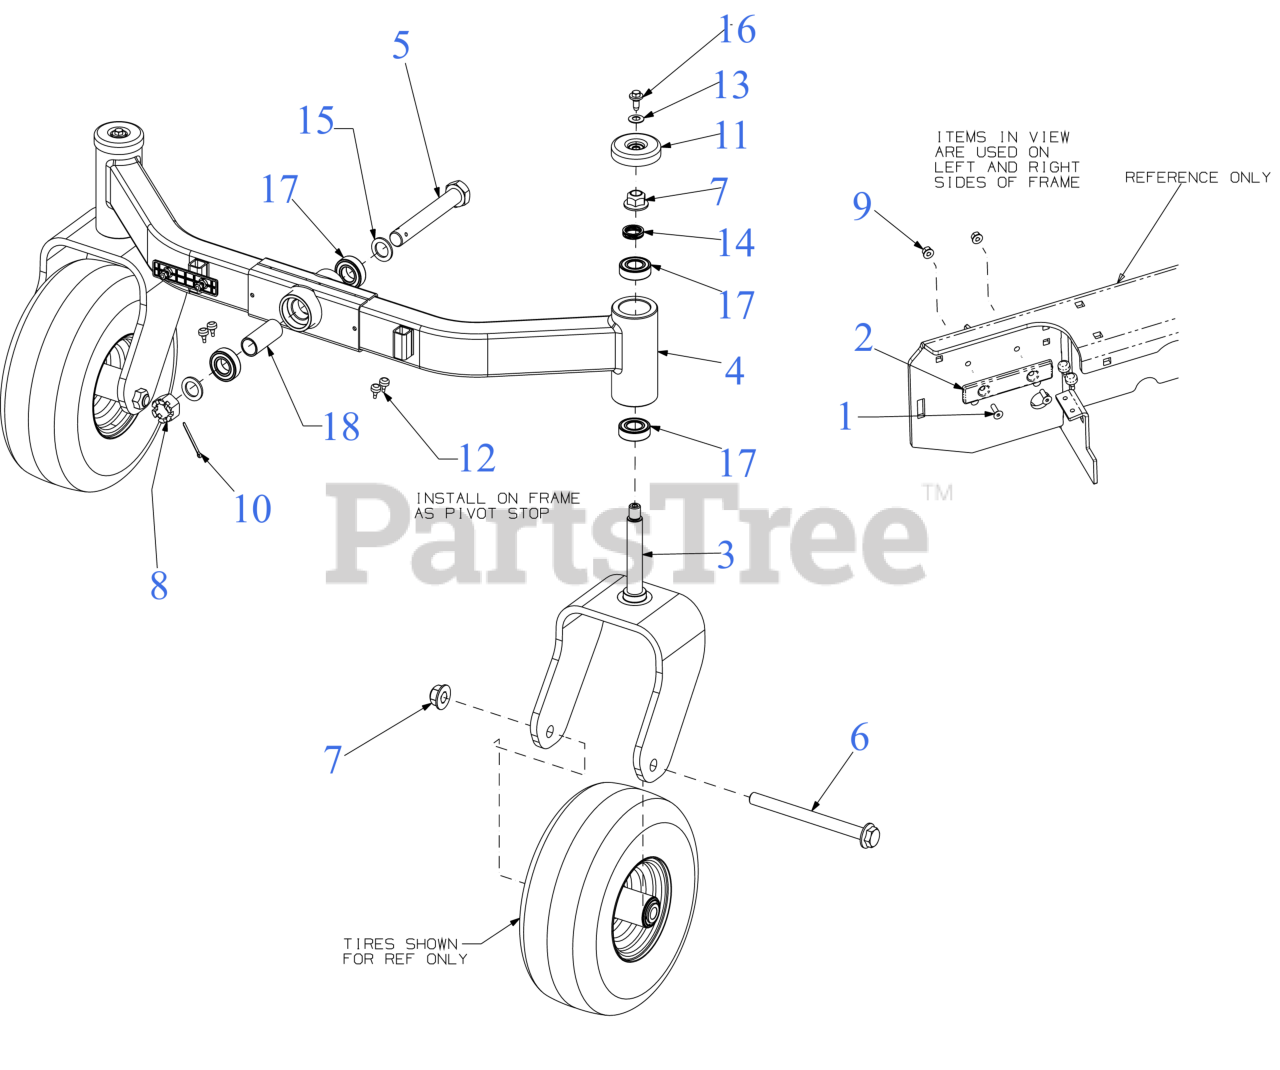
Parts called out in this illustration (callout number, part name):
1	SCREW-FLAT HEAD CA
2	PLATE-LIFT WEAR
3	FRONT CASTER ASSEMBLY
5	HEX HEAD SCREW (1-14 x 7 GR5)
6	SCREW 3/4-16 x 9.00 GR5
7	FLANGE LOCK NUT 3/4-16 TOP LOCK
8	CASTLE NUT 1.0-14 GR5
9	LOCK NUT 1/4
10	COTTER PIN
10	SPLIT COTTER PIN 5/32 X 2.00
11	AXLE CAP 3"
12	BUMPER, .62 DIA x .3
13	BELL WASHER
14	WAVE WASHER
15	FLAT WASHER 1.005 x 1.570 x 0.125
17	BALL BEARING (1.0 x 52 x 15)
18	SPACER 1.00 x 1.25 x 2.99
